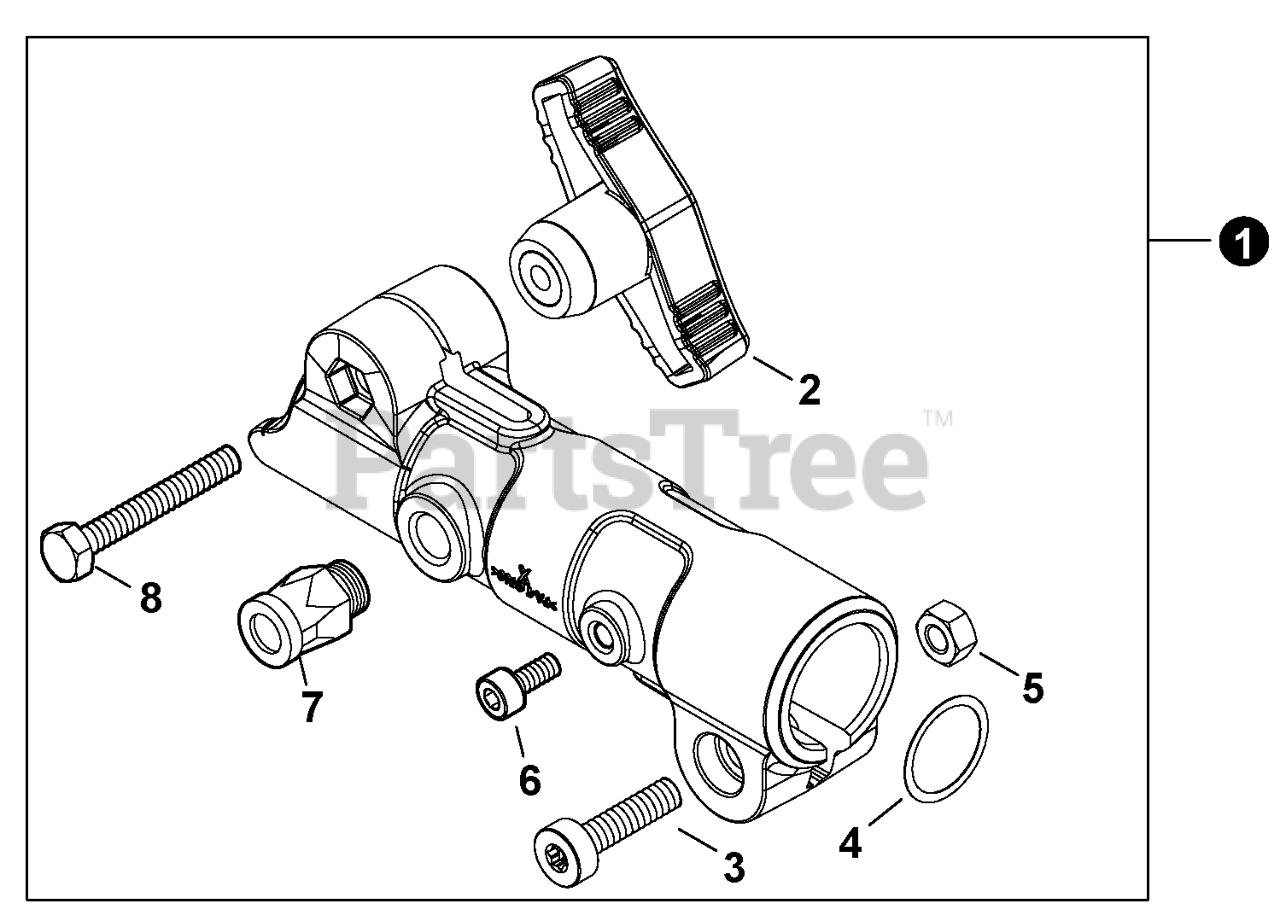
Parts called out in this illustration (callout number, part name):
1	COUPLER ASSY
2	THUMBSCREW
3	BOLT, TORX 6x25
4	WASHER 18 SPR STEEL
6	BOLT, TORX 5x12
7	LATCH ASSY
8	BOLT 6x40
